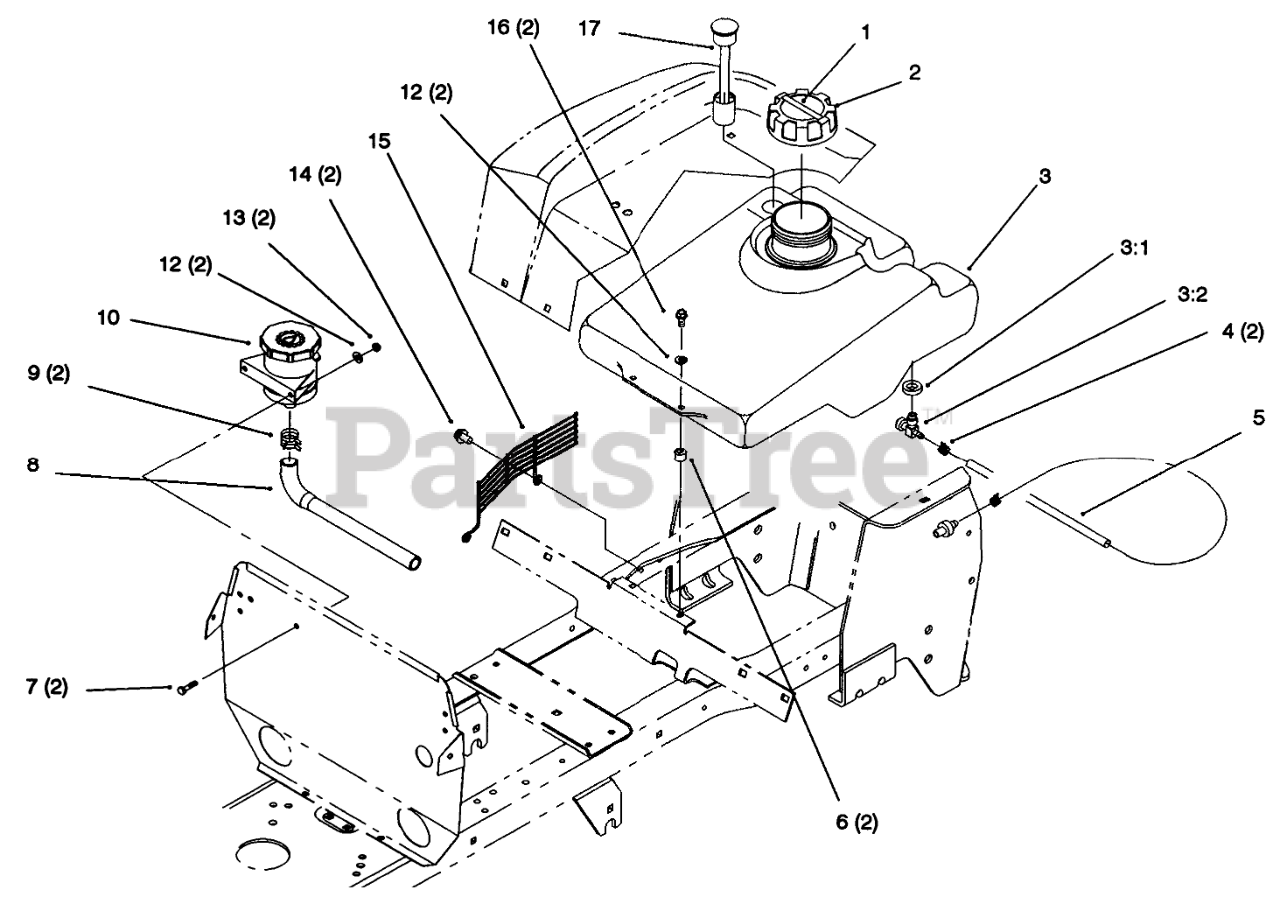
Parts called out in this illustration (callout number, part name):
2	GAS CAP ASM
3	TANK-FUEL
3:1	BUSHING
3:2	VALVE-FUEL
4	CLAMP-HOSE
5	HOSE - FUEL LINE TWIN
6	SPACER - FUEL TANK
7	SCREW-HH
8	HOSE - HYDRO
9	CLAMP-HOSE
10	ASS'Y-RESERVOIR
12	WASHER-FLAT
13	NUT-LOCK, NI
16	SCREW-HH
17	SENSOR-FUEL, LOW
